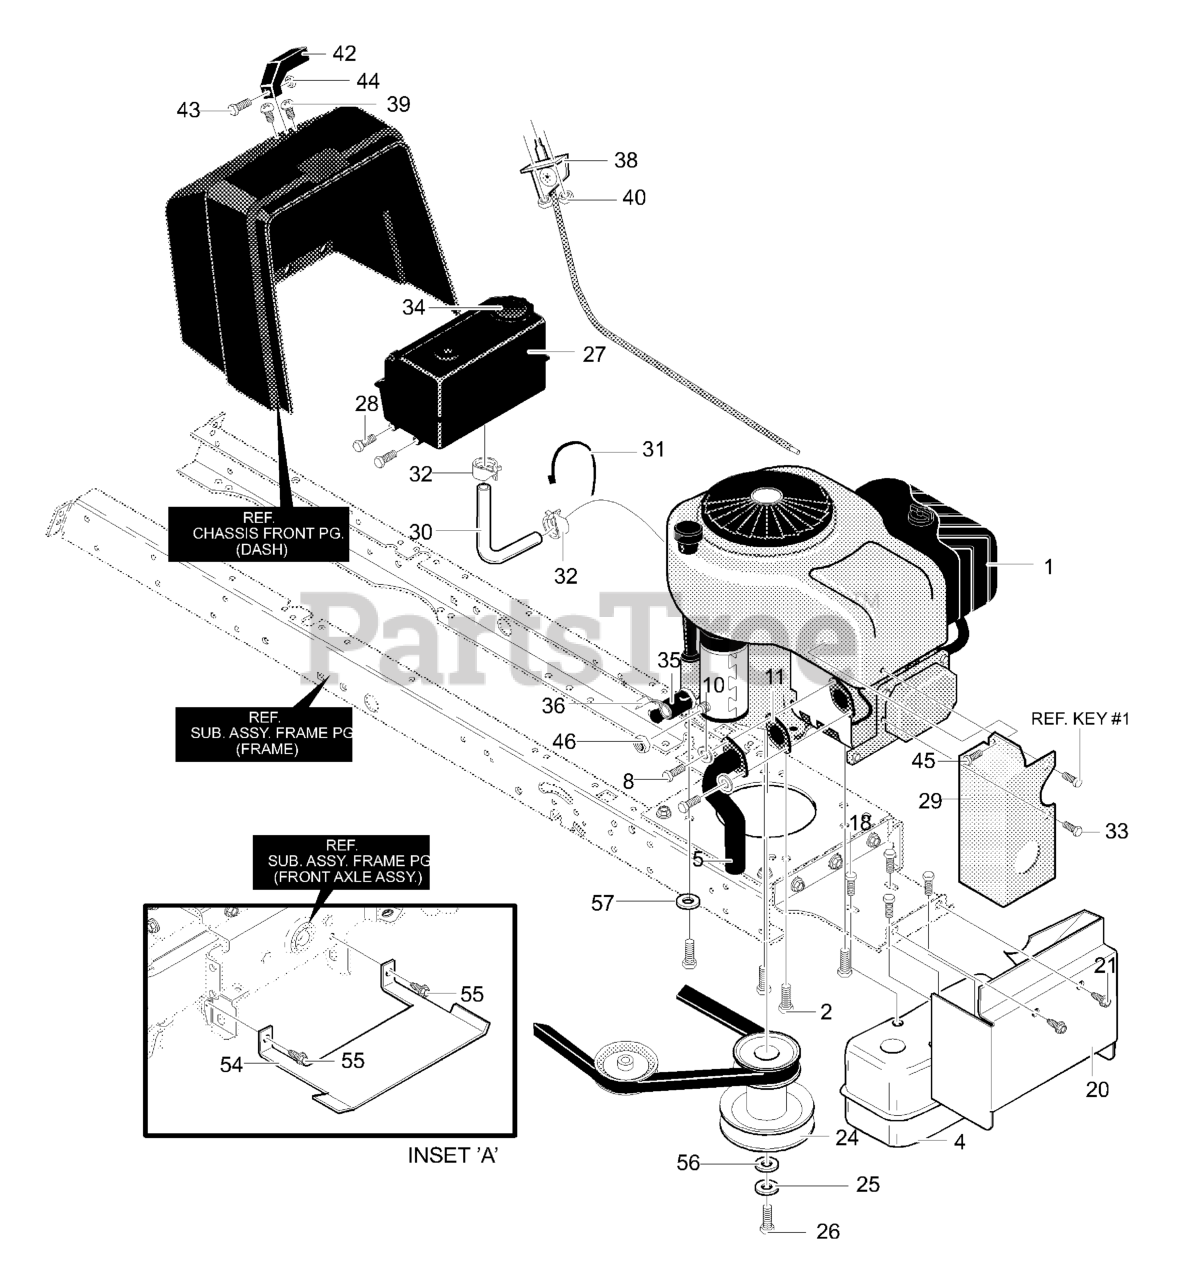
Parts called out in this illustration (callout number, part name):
2	Engine Bolt
4	Muffler, Single Cylinder
5	Exhaust Tube
8	Screw, 5/16-18 x .75
10	Washer, Hvsptlk
11	GASKET, Exhaust
18	Screw, 1/4-20x.63
20	Heat Shield Lower Front
21	Screw, 5/16-18 x .75
24	Stack Pulley
25	Washer, Regsptlk
26	Screw, 7/16-20
27	Tank, Fuel 1.5 Gal.
28	Screw, 15tpx
29	Heat Shield, Side
30	Gas line 12 Inches
31	Cable Tie
32	Clamp, Fuel Clamp
33	Screw, 1/4-20x.50
34	Gas Cap
35	Oil Drain Valve Assembly
36	Cap, Oil Drain Valve
38	Throttle Control
39	Screw, 10-24x.63
40	Nut, #10-24
42	Knob, Throttle Control
43	Screw, #8-32
44	Nut, #8-32
45	Screw, 10-16x.50 Drill
46	Nut, 1/4-20
54	Shield, Anti-Dehydration
55	Screw, 5/16-18 x .75
56	Flatwasher, .480x1.00
57	Washer, Exlk
